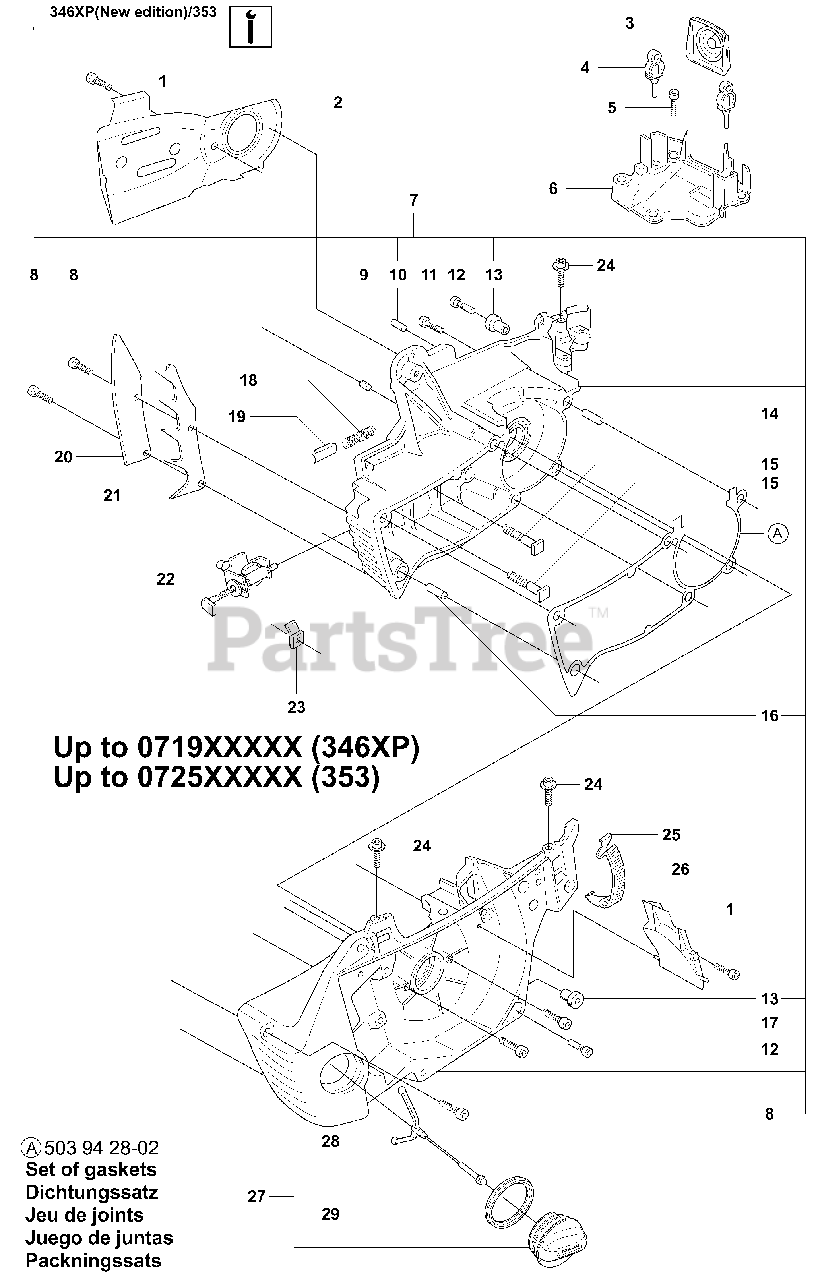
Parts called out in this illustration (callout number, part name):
7	CRANKCASE ASSY.
13	MOVEMENT LIMITER
18	LOCK SPRING
21	FELLING DOG
22	CHAIN TENSIONER
23	CHAIN CATCHER
25	BUCKLE ORANGE
27	OIL TANK CAP GREY
29	OILCAP GASKET
A	GASKET SET
